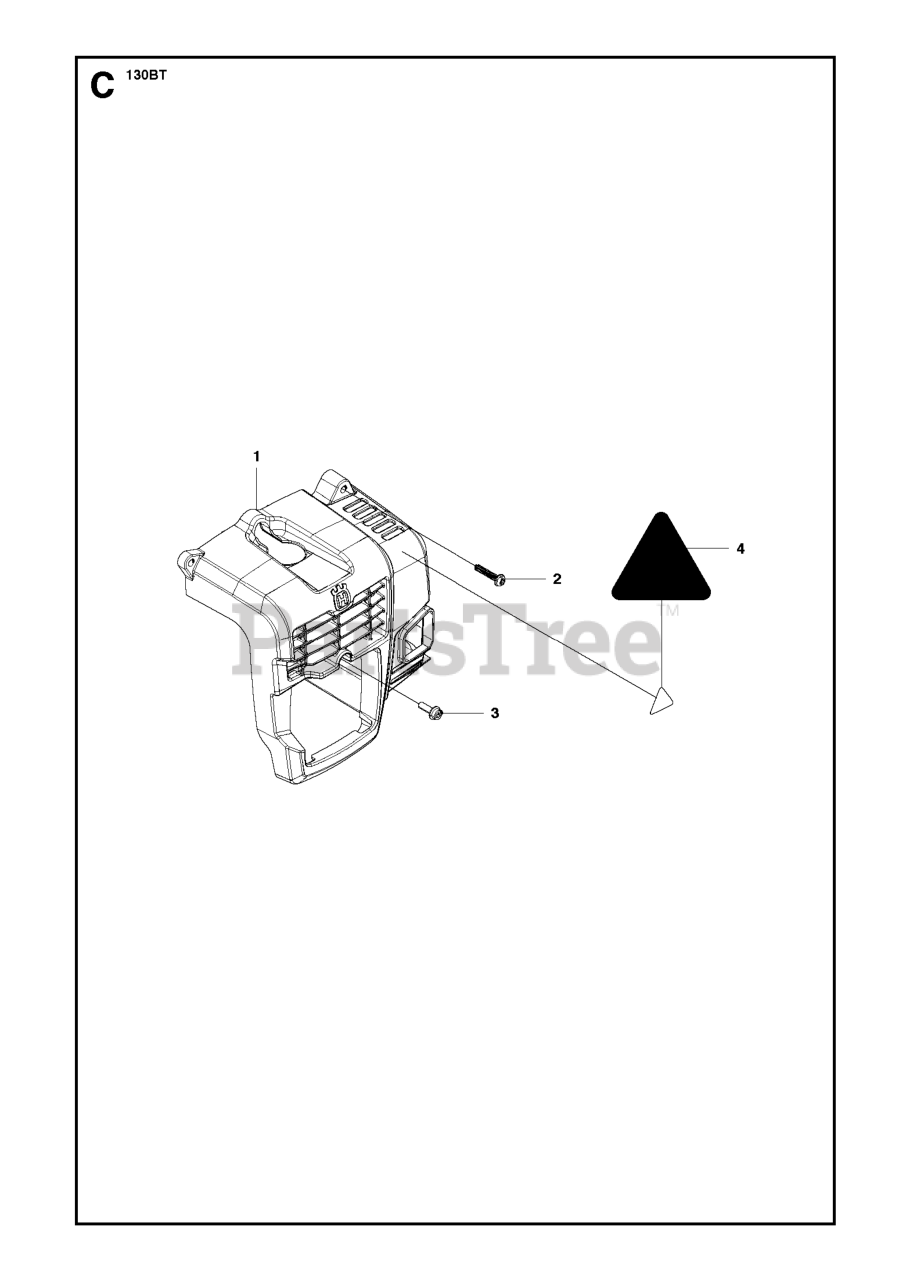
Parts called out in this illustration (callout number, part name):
1	ENGINE COVER
2	SCREW
3	BOLT
4	RP_LABEL, HOTMARK
